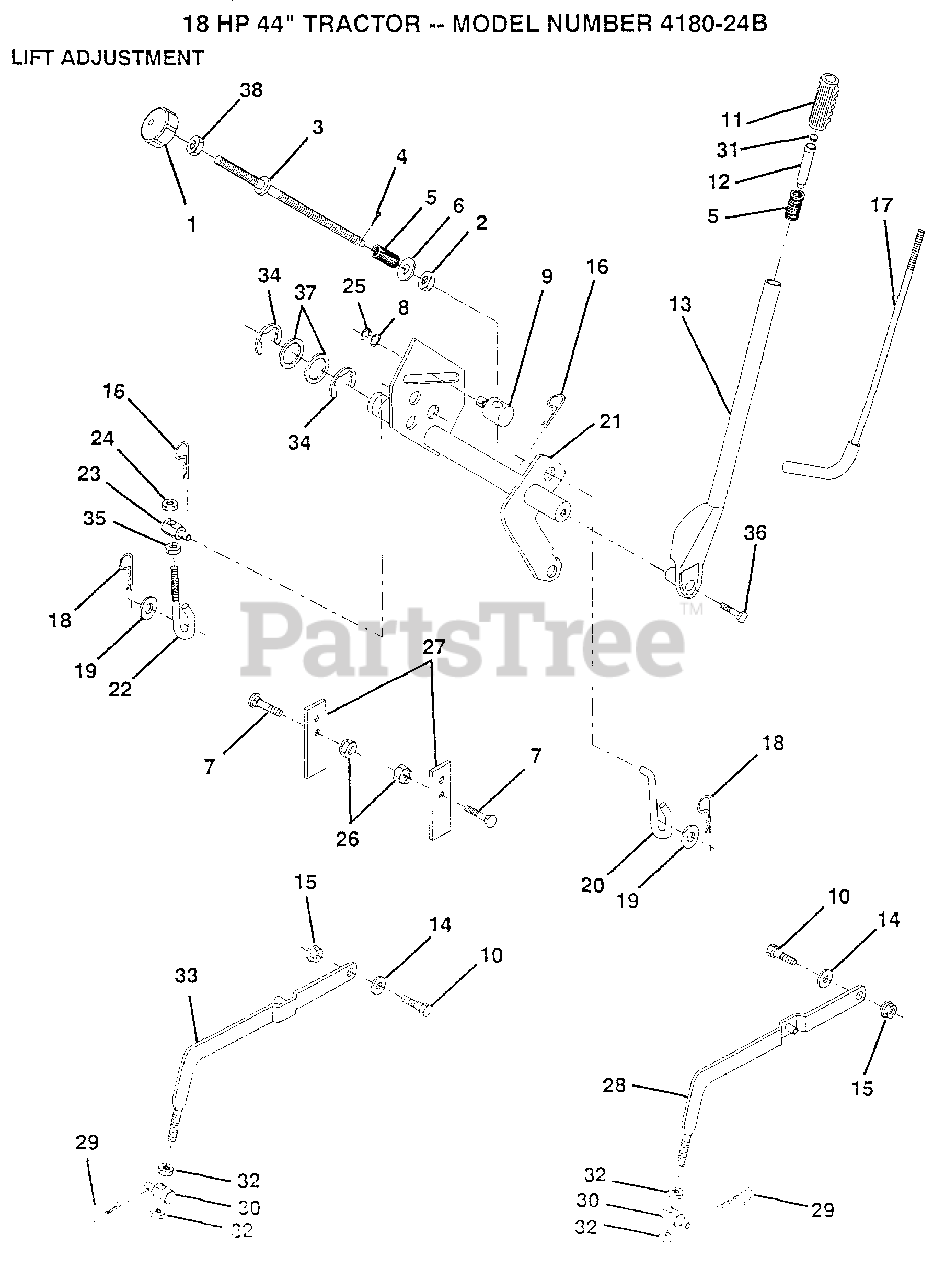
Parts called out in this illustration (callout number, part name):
1	HDLE ADJ LIFT
2	NUT T
3	ROD LIFT LT
5	SPRING T
6	WASHER
8	WASHER
9	TRUNION LT
10	"BOLT, SHOULDER LT"
11	GRIP
14	WASHER T
15	NUT SPECIAL T
17	LEVER ROD LT
18	SPRING.RETAINER
20	LIFT LINK LT
21	LIFT SHAFT ASM
22	PIVOT PIN T
25	KLIP RING
27	UPSTOP
28	RH SUSP ARM ASM
29	SPRING H
32	NUT
33	LH SUSP ARM ASM
34	E-RING
35	NUT
36	"BOLT,HEX"
37	WASHER
38	NUT
